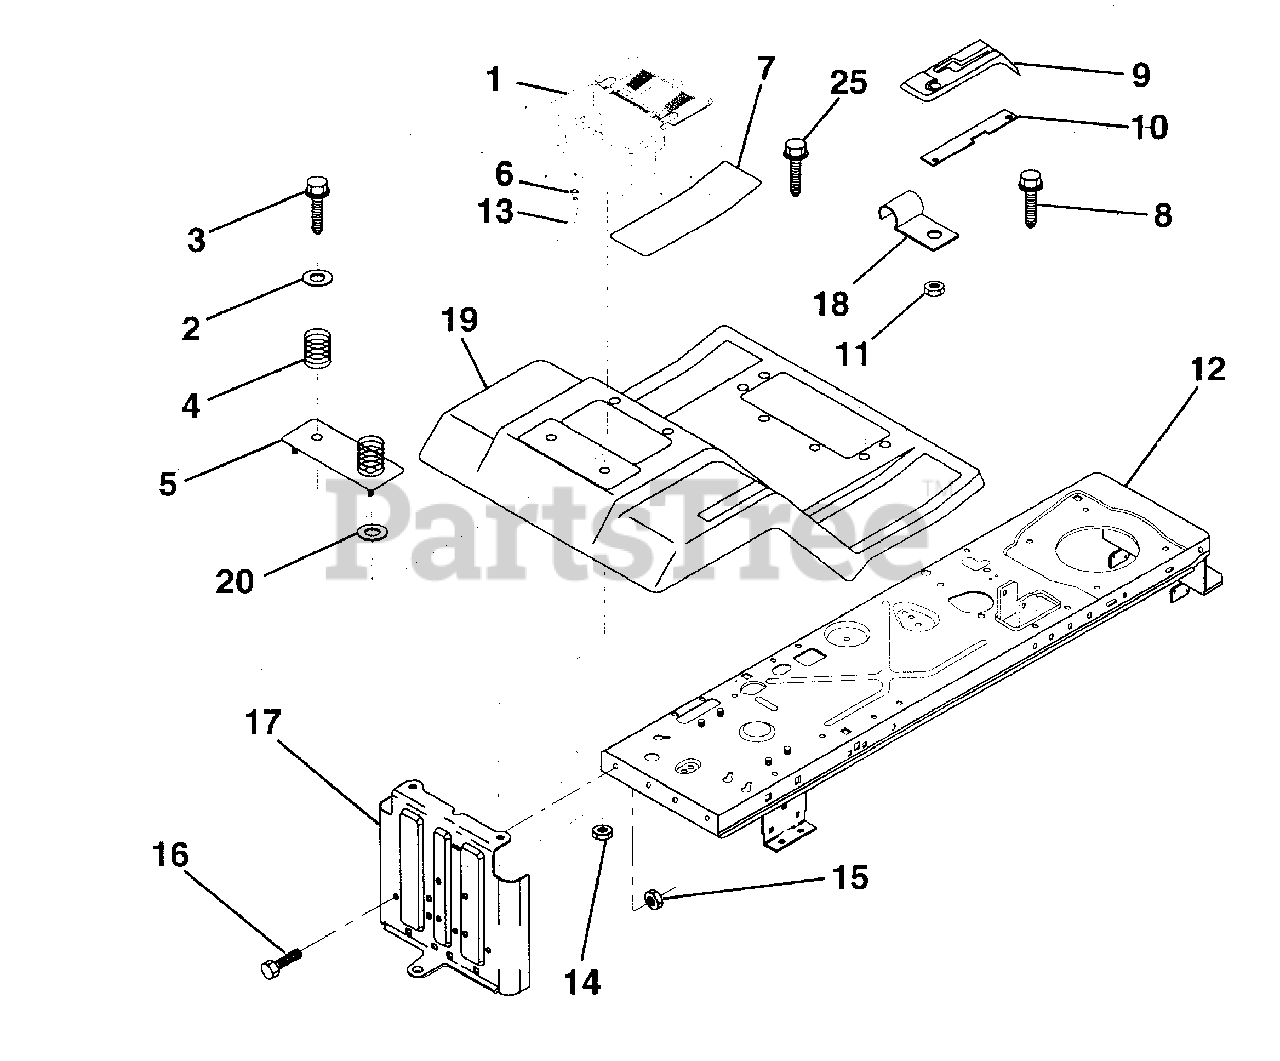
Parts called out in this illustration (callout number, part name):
1	Case, Battery
2	Washer 13/32 x 1-1/4 x 12 Ga.
3	Screw, Hex Wsh. Thrdrol 3/8-16 x 3/4
4	Spring, Compression, Seat
5	Plate, Asm. Battery
6	Clamp, Hose
7	Pad, Footrest
8	Screw Thdrol 5/16-18 x 3/4
9	Console, Shift Control
10	Bar, Shift Lock
11	Nut, Self-Threading, Wsher Hd 3/16
12	Assembly, Frame
13	Tube, Battery Drain
14	Nut, Keps 1/4-20 UNC
15	Nut, Crownlock 5/16-18
16	Bolt, Hex Hd. 5/16-18 UNC x 3/4
18	Clip, Insulated
19	Fender/Footrest
20	Washer 9/32 x 7/8 x 13 Ga.
25	Scr-Hx Wsh Thd Rol 5/16-18 x 1
